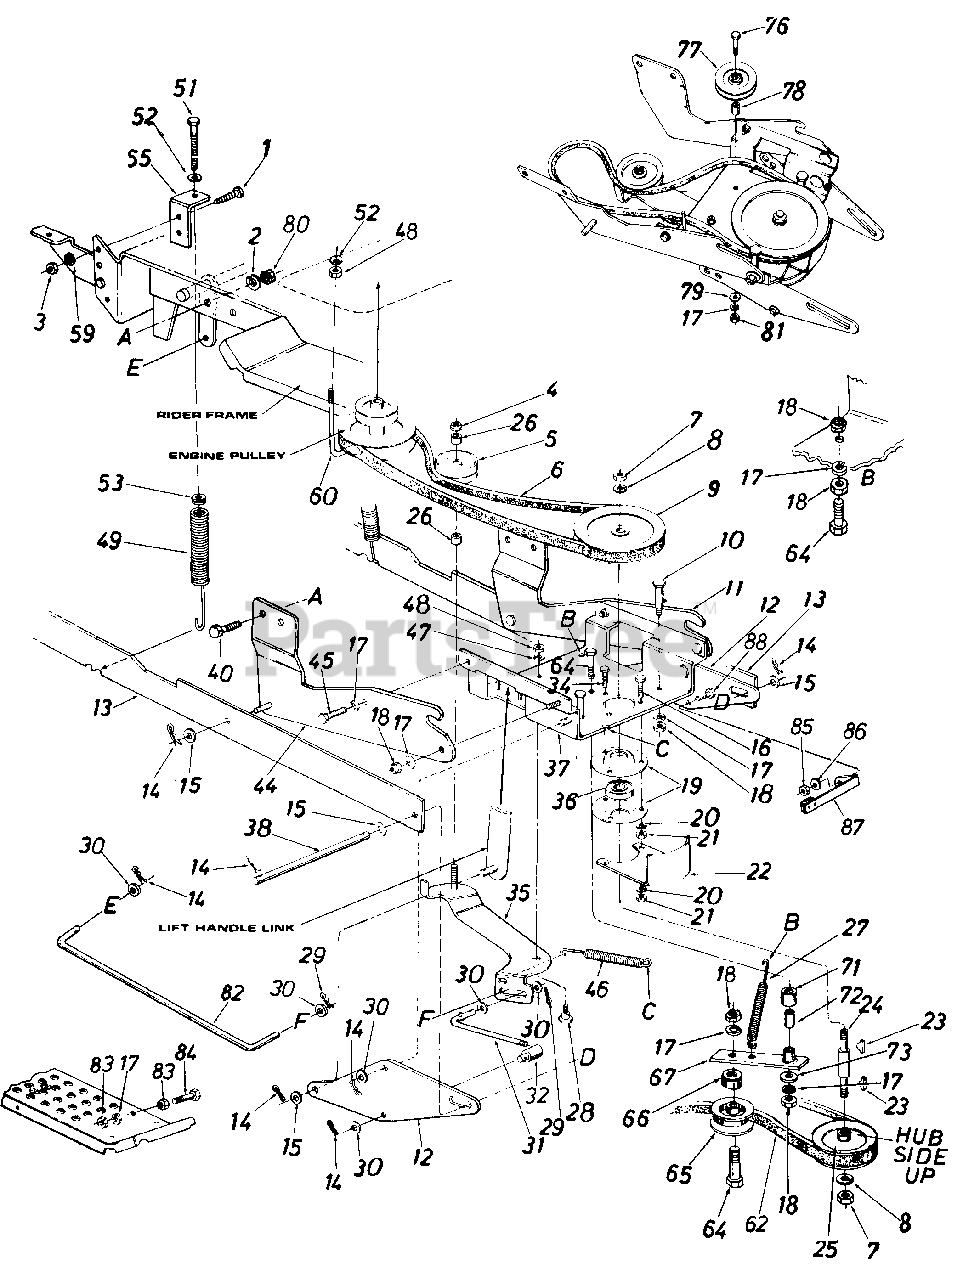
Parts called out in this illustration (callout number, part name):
1	Hex Bolt 1/4-28 x 1.0" Lg. Gr. 5
2	L-Wash. 1/4" I.D.
3	Hex Nut 1/4-28 Thd.
4	Hex Cent. L-Nut 3/8-16 Thd.
5	Idler Pulley
6	"V"-Belt
7	Hex Jam Nut 5/8-11 Thd.
8	L-Wash. 5/8" I.D.
9	5/8 Pulley x 6.5" O.D.
10	Shoulder Bolt
11	Channel Support Brkt. R.H.
12	Linkage Brkt.
13	Linkage Arm Ass'y.
14	Intern. Cotter Pin .50" Dia.
15	Fl-Wash.
16	Hex Bolt 5/16-18 x 1.25" Lg.
17	L-Wash. 3/8" I.D.
18	Hex Jam Nut 3/8-16 Thd.
19	Bearing Housing
20	L-Wash. 5/16" I.D.
21	Hex Nut 5/16-18 Thd.
24	Pulley Spindle
25	5/8 Pulley 6.28" I.D. x 5.56" O.D.
26	Spacer.383" I.D. x.503" O.D. x .562" Lg .
27	Extension Spring .54" O.D. x 5.25"
28	Shoulder Bolt
29	Cotter Pin 3/32" Dia.
30	Fl-Wash.
31	Control Rod (Clutch)
32	Ferrule
34	Hex Sems Bolt 5/16-18 x .75" Lg.
35	Clutch Idler Brkt. Ass'y.
36	Ball Bearing
37	Channel Ass'y.
38	Lift Handle Shaft
40	Hex Self-Tap Scr. 1/4-20 x .75" Lg.
44	Channel Supporting Brkt. L.H.
45	Hex Bolt 3/8-16 x 1" Lg.
46	Extension Spring
47	L-Wash. 5/16" I.D.
48	Hex Nut 5/16-18 Thd.
49	Helper Spring
51	Hex Bolt 5/16-18 x 2.0" Lg. Special
52	Bell-Wash. .345" I.D. x .88" O.D. x .06"
53	Spring Insert
60	J-Bolt 5/16-18 Thd.
62	"V"-Belt
64	Hex Bolt 3/8-16 x 2" Lg.
65	Idler Pulley
66	Spacer .385" I.D. x .503" O.D. x .562" Lg.
67	Idler Arm Ass'y.
71	Spacer.38" I.D.
72	Spacer .3775" I.D. x .6" O.D. x 8.3" Lg.
73	Fl-Wash. 3/8" I.D. x 1" O.D. x 1.27"
76	Hex Bolt 3/8-16 x 2.5" Lg. (Grade 5)
77	Idler Pulley .38" I.D. x 3.06" O.D.
78	Spacer .385" I.D. x .63" O.D. x.76" Lg.
79	Fl-Wash. .39" I.D. x 1-3/4 O.D. x 3/16"
80	Hex L-Nut 1/4-20 Thd.
81	Hex Nut 3/8-16 Thd.
82	Clutch Control Rod
83	Hex Nut 3/8-24 Thd
84	Hex Bolt 3/8-24 x 2.25" Lg.
85	Hex Nut 3/8-16 Thd.
86	Bell-Wash. 3/8" I.D.
87	Auger Brake Brkt. Ass'y.
88	Hex Bolt 3/8-16 x 5/8" Lg.
